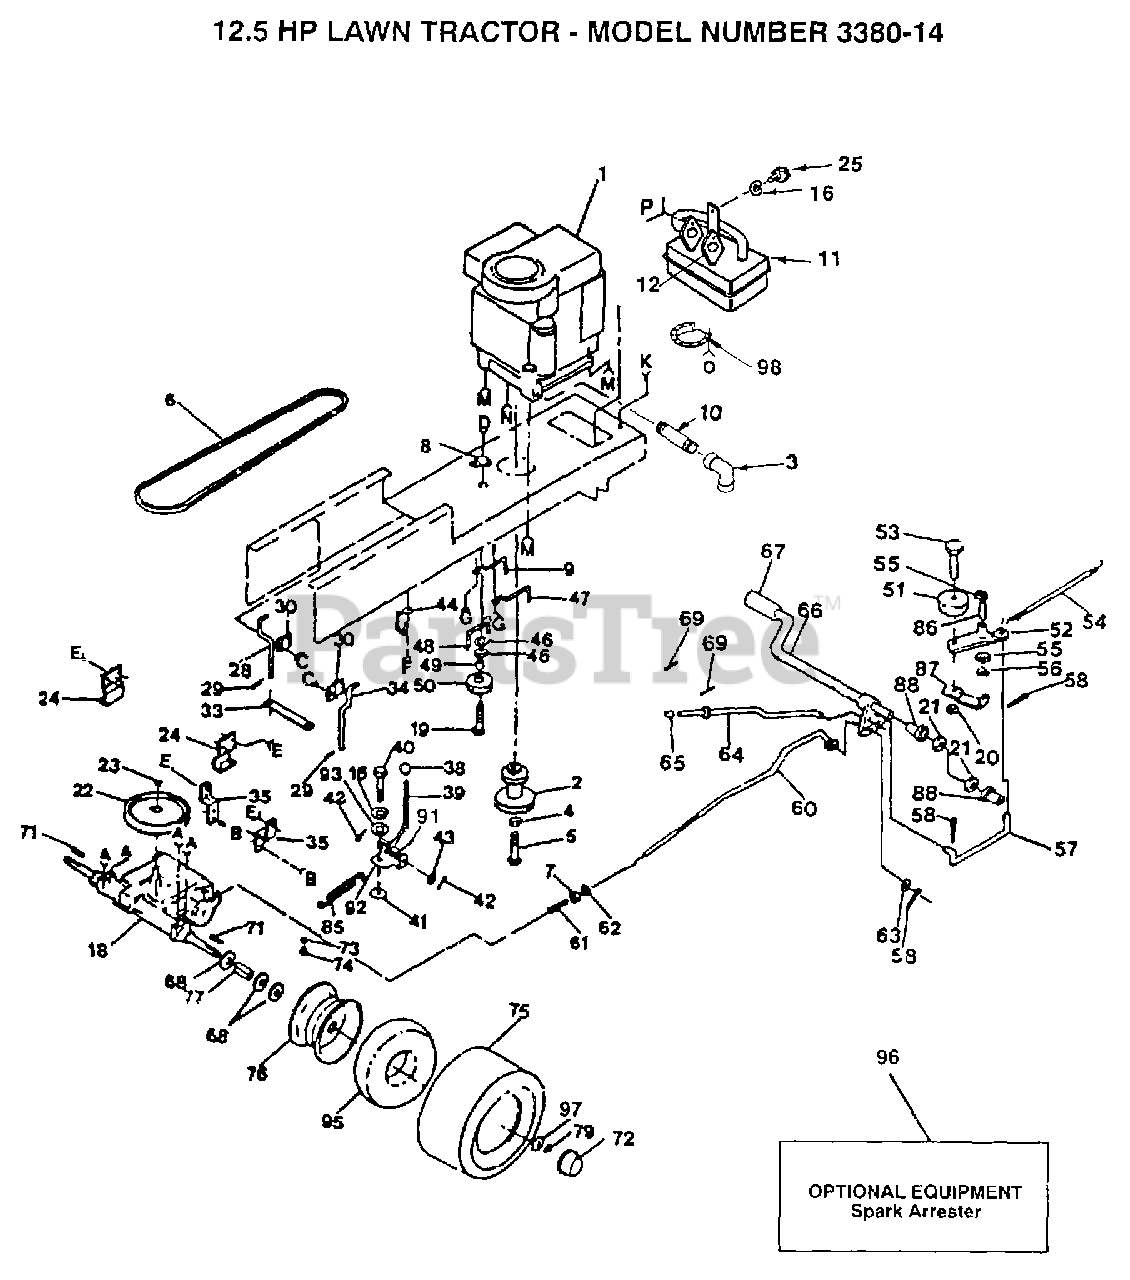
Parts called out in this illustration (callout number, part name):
3	ELBOW
4	LOCKWASHER
5	BOLT
6	BELT-V.90.0.GD.DR
7	NUT
8	CLIP T
9	KEEPER BELT ENGLH
10	PIPE NIPPLE
11	MUFFLER LT
16	LOCKWASHER
19	BOLT
21	WASHER LT
22	PULLEY TRANS
24	BRACKET LT
25	BOLT
28	KEEPER BELT LH
29	SPRING.RETAINER
30	CLAMP LT
33	STRAP LOCATOR
34	KEEPER BELTRH
35	STRAP TORQUE
38	KNOB T (1/2-HOLE)
39	ROD SHIFTER
41	WASH-SHFT PLT LT
42	PIN COTTER 1/8
43	WASHER
46	WASHER
47	"KEEPER,BLT ENG LT"
48	BELT KEEPER LT
49	SPACER T
50	PULLEY.IDLER.FLAT
52	ARM IDLER
54	"SPRING, RETURN LT"
55	WASHER LT
56	KLIP RING
57	"LINK, CLUTCH T"
58	COTTER PIN
60	BRAKE ROD LT
61	SPRING ROD LT
62	NUT
63	WASHER
65	PLUNGER CAP T
67	PEDAL COVER T
68	WASHER
71	SQUARE KEY
72	HUB CAP
73	VALVE CAP
74	VALVE STEM LT
77	SPACER LT
79	E-RING LT
86	"LY, BEARING"
87	RETAIN BELT
88	NYLON BEARING
91	SPRING LT
92	PLATE SHIFT LT
93	WASHER LT
95	TUBE.18X9.5-8
96	SPARK ARREST KIT
97	WASHER
98	DEFLECTOR.222573
